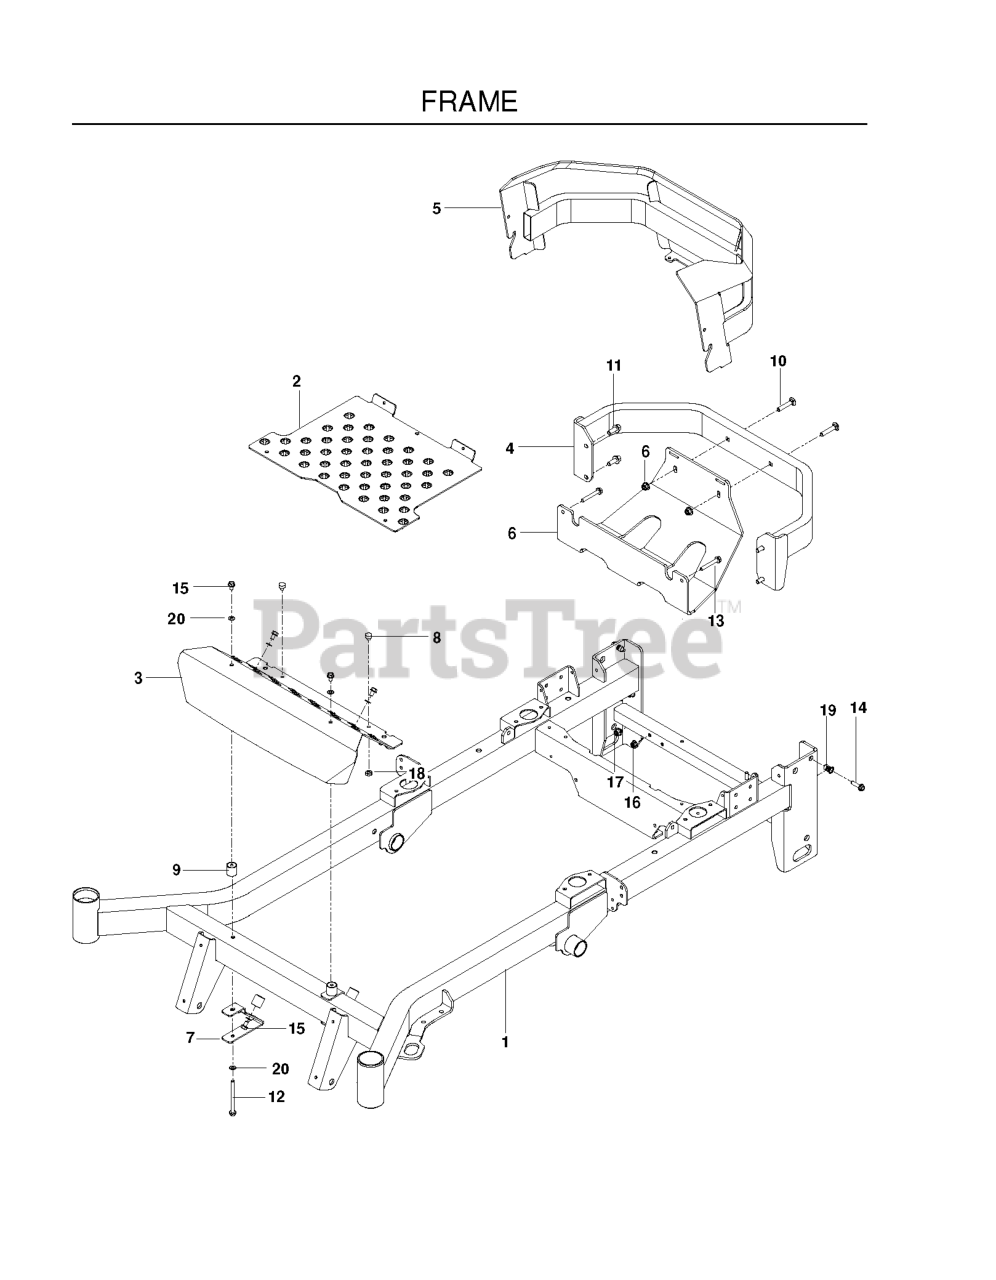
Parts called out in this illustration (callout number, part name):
1	FRAME W/DECALS, PZ
2	PLATE, FLOOR PAN, OR
3	PLATE, FOOT REST, OR
4	BUMPER.REAR.ORANGE
5	GUARD, REAR, GRAY
6	PLATE, SKID GRAY
7	BRACKET, REST MOUNT
8	BUMPER, 1/4-20 STUD, 1/4
9	MOUNT, F/F INSERT
10	RHSNB 3/8C X 2
11	HHFS 3/8-16 X 1 GRD 5 ZD
12	HHFS 5/16-18 X 3 3/4
13	HHFS 5/16-18 X 2.25 GD 5
14	HHFS 5/16-18 X 1.25 TPBLT GD 5
15	SCR 5/16-18 X 1/2 SELFTAP ZN
16	5/16-18 NYLOC FLANGE NUT
17	NUT 3/8-16 HEX FLG NYLOC ZD
18	JAM NUT 1/4C (2 2 PW01)
19	NUTSERT 5/16-18 THICK GRIP
20	WASH 5/16 DISC SPRING ZD
